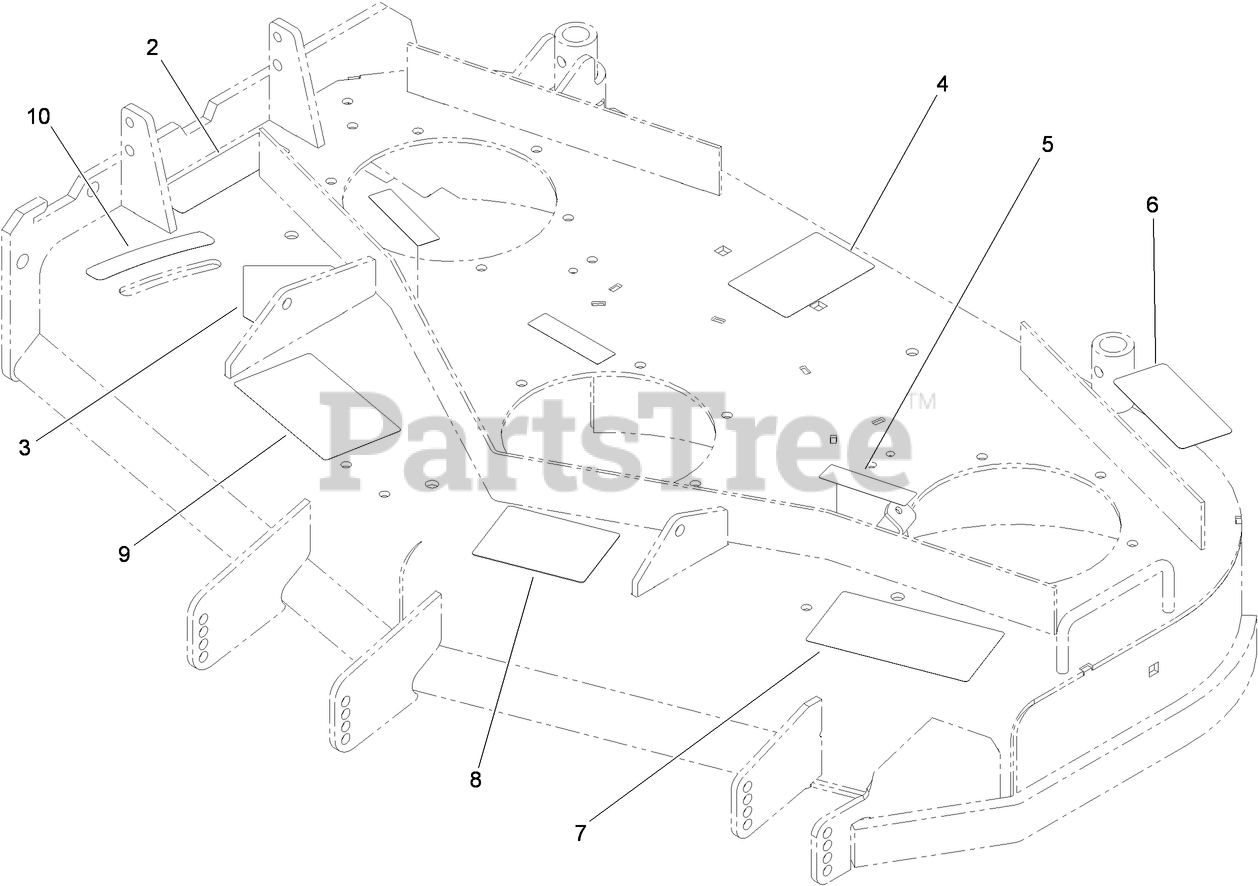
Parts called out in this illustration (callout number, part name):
2	DECAL-WARNING
3	DECAL-DANGER
4	DECAL-ROUTING, BELT
5	DECAL-COVER, MISSING
6	DECAL-TORQUE
7	DECAL-DANGER, THROWN OBJECT
8	DECAL-SCALP, ANTI
9	DECAL-ADJUSTMENT, BAFFLE
10	DECAL-SETTING, BAFFLE
